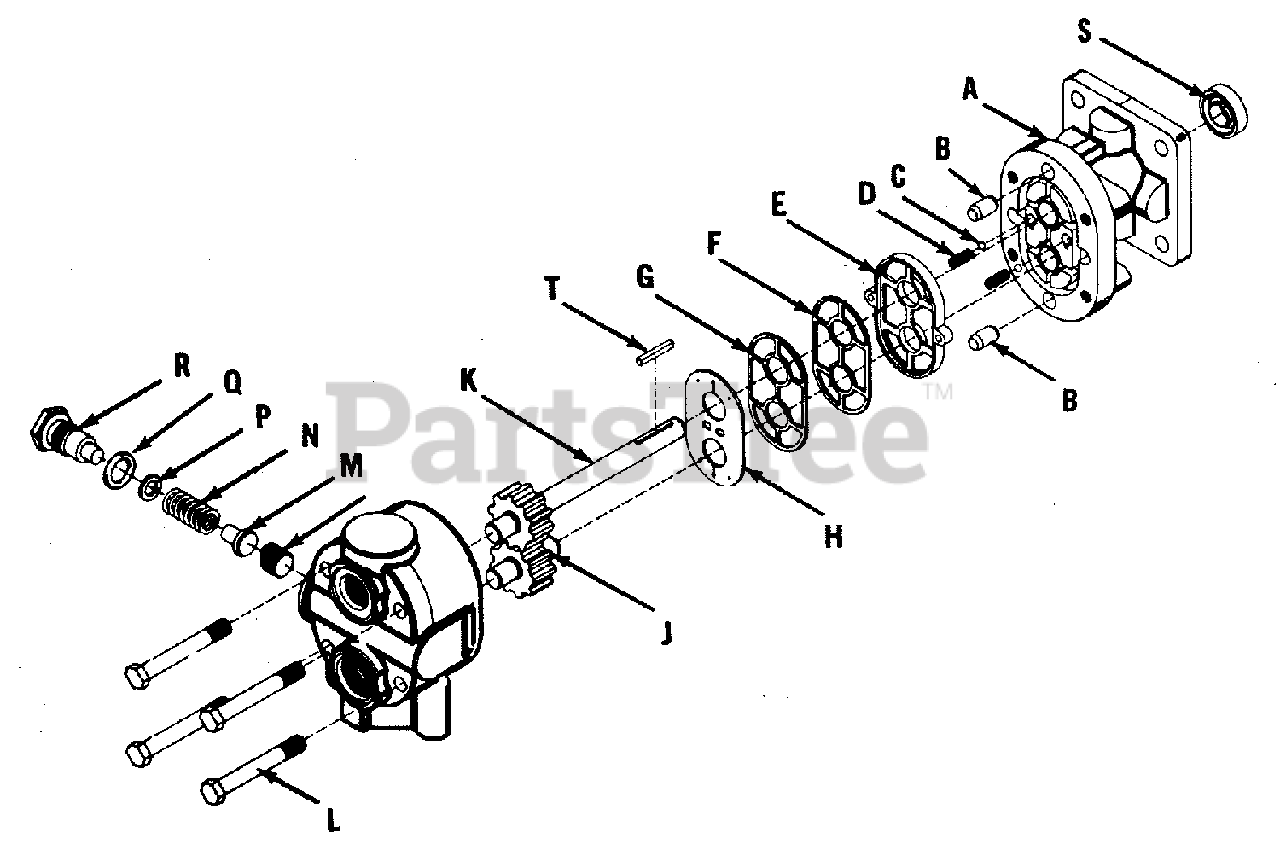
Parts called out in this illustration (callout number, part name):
A	FRONT PLATE ASSEMBLY
B	PIN, Dowel
C	BALL, Steel
D	SPRING, Check
E	SEAL, Diaphragm
F	GASKET, Protector
G	GASKET, Back-up
H	DIAPHRAGM
J	IDLER SHAFT ASSEMBLY
K	DRIVE SHAFT ASSEMBLY
L	SCREW, Hex, Cap, 1/4"-20 NC x 2"
N	SPRING, Relief
Q	RING, "O"
R	PLUG, Hex
S	SEAL, Shaft
U	BACK PLATE REPAIR KIT
V	MAJOR SEAL REPAIR KIT
